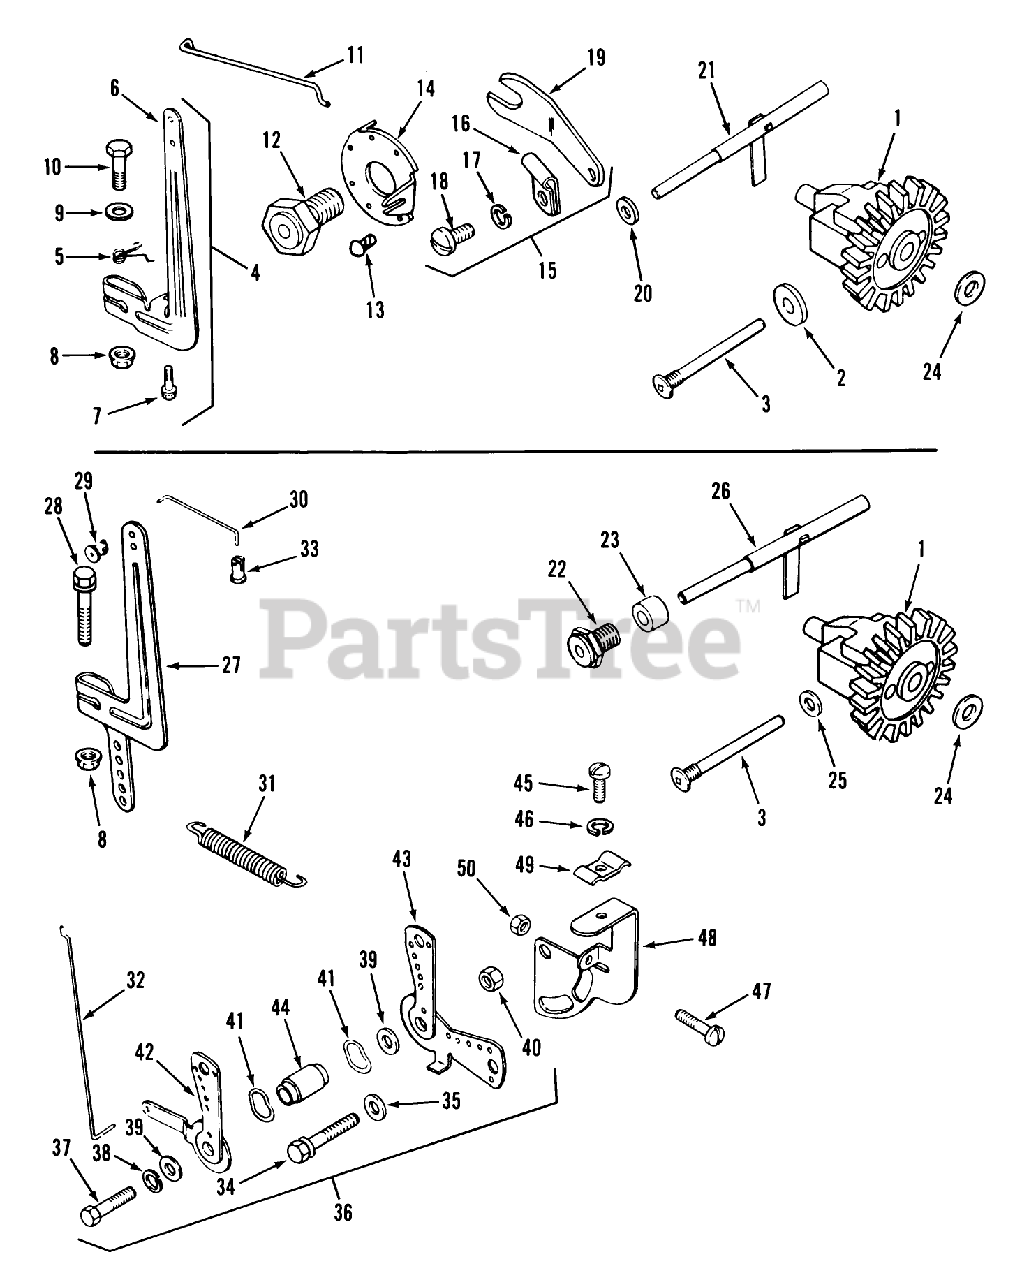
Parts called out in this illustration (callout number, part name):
1	KOHLER A-235743-5
2	KOHLER X-25-12
3	KOHLER 231355
4	KOHLER A-234178
5	KOHLER 232617
6	KOHLER 232614
7	KOHLER X-67-46
8	KOHLER X-799-1
9	KOHLER X-25-72
10	KOHLER X-5-7
11	KOHLER 230078
12	KOHLER 230476
13	KOHLER X-67-5
14	KOHLER 220766
15	KOHLER A-234857
16	KOHLER 210149
17	KOHLER X-18-1
18	KOHLER X-51-12
19	KOHLER 232888
20	KOHLER X-25-58
21	KOHLER 230540-5
22	KOHLER 235476
23	KOHLER X-400-80
24	KOHLER 237022
25	KOHLER 47-099-04
26	KOHLER A-235256-5
27	KOHLER 47-090-20
28	KOHLER X-776-1
29	KOHLER 47-158-07
30	KOHLER 47-079-05
31	KOHLER 47-091-01
32	KOHLER 47-079-01
33	KOHLER # 25-158-07
34	KOHLER X-132-6
35	KOHLER X-25-72
37	KOHLER X-5-26
38	KOHLER X-20-1
39	KOHLER X-25-63
40	KOHLER X-76-2
41	KOHLER 275690
42	KOHLER 47-090-07
43	KOHLER 47-090-08
44	KOHLER 47-112-02
45	KOHLER X-15-5
46	KOHLER X-19-1
47	KOHLER 232556
48	KOHLER 47-126-09
49	KOHLER 47-237-02
50	KOHLER X-72-4
